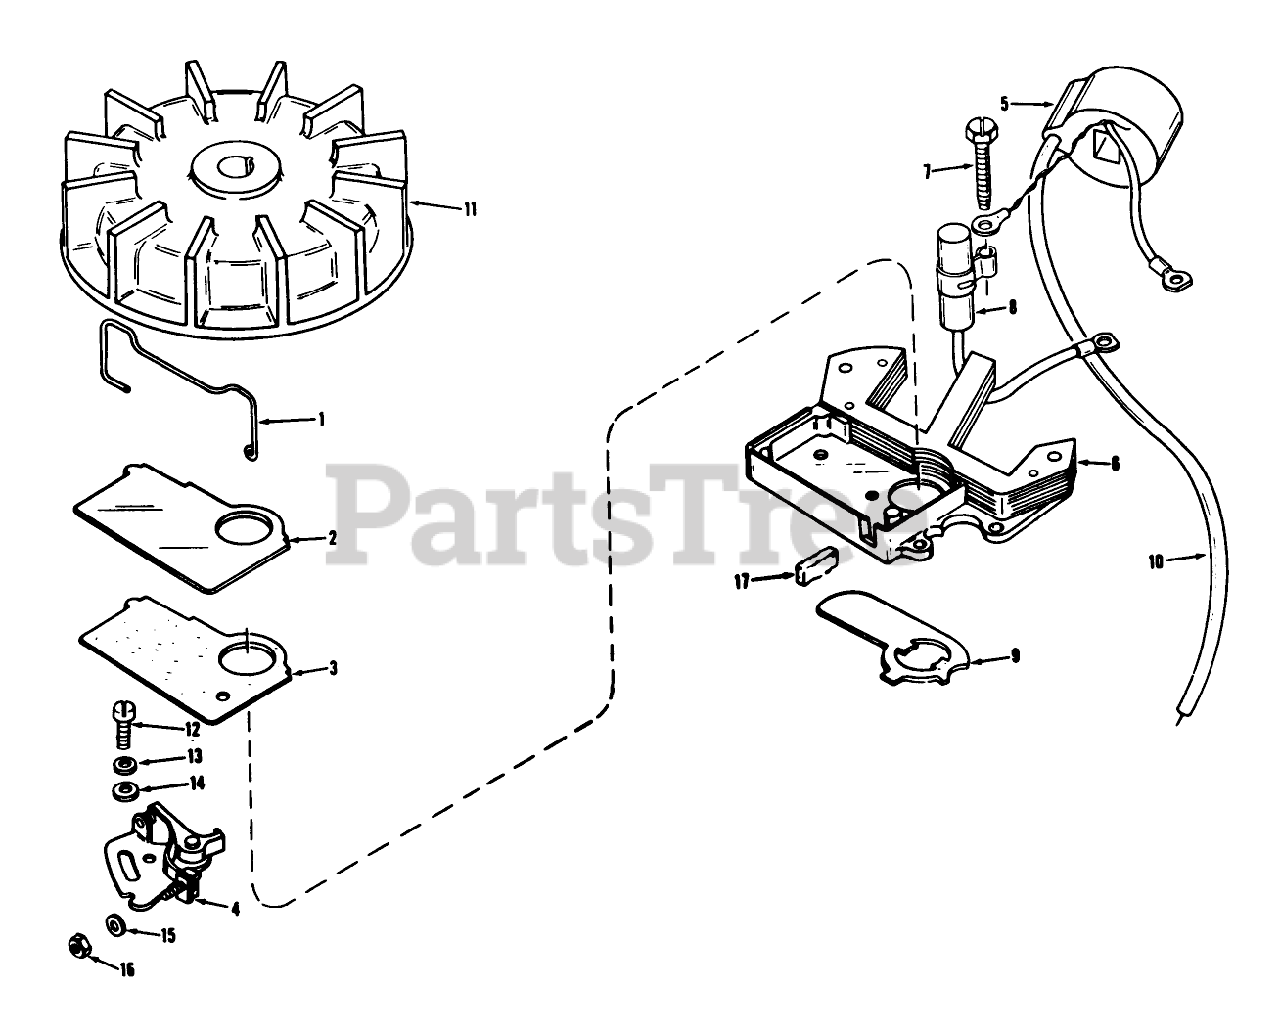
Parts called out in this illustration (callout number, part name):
1	Dust Cover Spring
2	Dust Cover
3	Dust Cover Gasket
4	Hose-Primer 209543
5	Coil Assy.
6	Gasket 209542
7	Condenser Screw
8	Condenser Assy.
9	Sealing Washer
10	Wire, Lead
11	RETAINER WASHER
12	Fuel Hose
13	Fuel Tank
14	Flatwasher
15	Washer
16	DECAL
17	Cam Felt
